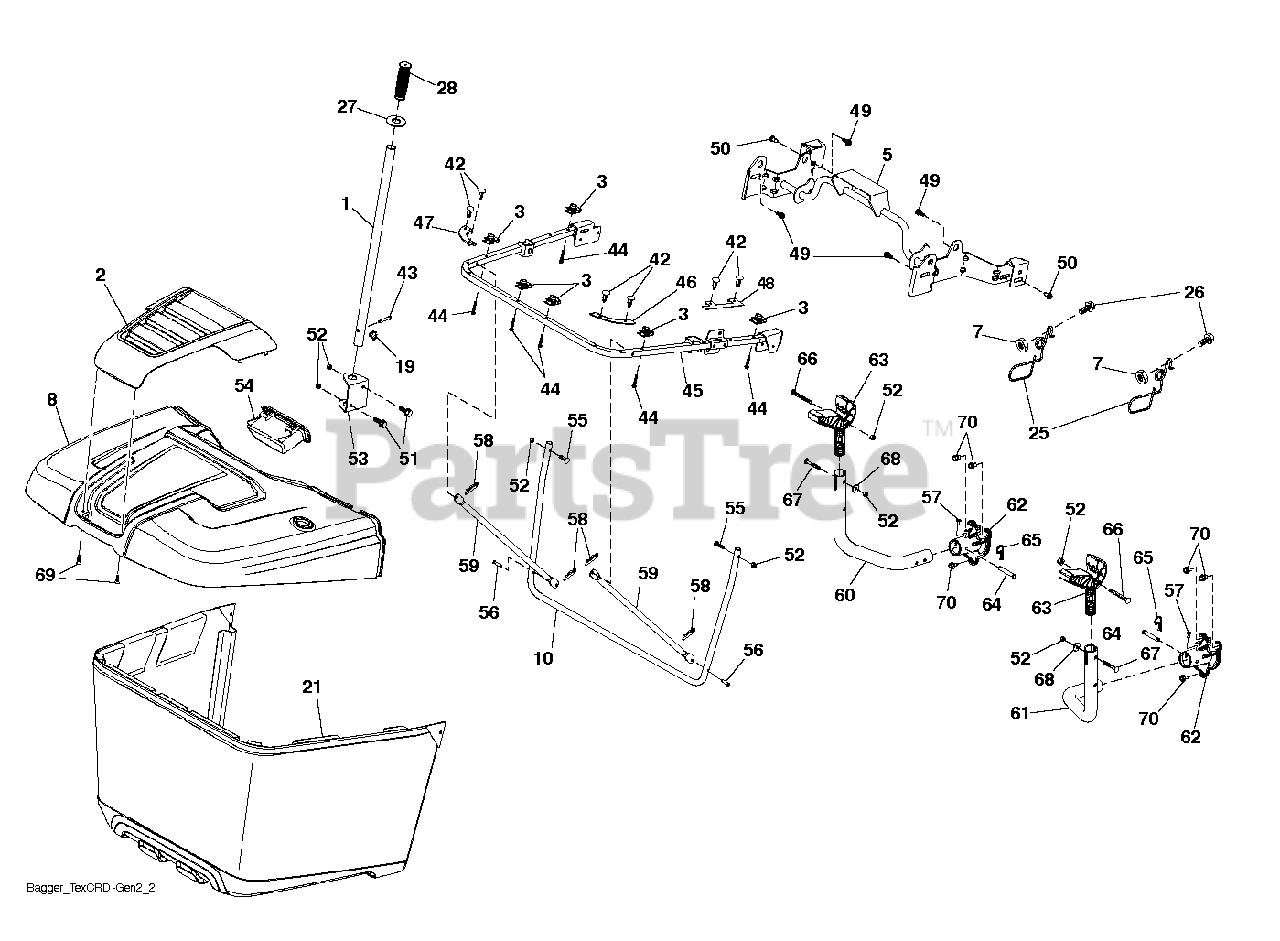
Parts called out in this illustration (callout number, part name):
1	TUBE.HANDLE.BAGGER.CRD/SRD.BLA
2	APPLIQUE.BAGGER
3	1/4-20 U NUT
5	FRAME TEX_CRD_GEN2 UPPER PIVOT
7	NUT T
8	BAGGER TOP
10	FRAME TEX_CRD_GEN2 BAGGER FRAM
19	PIN.COTTER.5/16.BOW TI
21	BAG FRAME BAGGER ASSEMBLY. HUS
25	LATCH LATCH. BAG. CRD GEN 2
26	SCREW HEX CRT
27	GROMMET RUBBER GROMMET, DUMP T
28	GRIP.HANDLE.BLACK
42	CLIP CHRISTMAS TREE CLIP
43	RIVET,DRILLED
45	FRAME TEX_CRD_GEN2 UPPER U FRA
46	CONNECTOR RIGHT BAGGER CORNER
47	CONNECTOR LEFT BAGGER CORNER C
48	BAFFLE BAGGER SIDE CLOSE-OUT
49	BOLT, SHOULDER 5/16-18
50	BOLT, 5/16-18 X 1 3/4
51	BOLT.CARR.SQNK.5/16-18UNC.X3/4
52	NUT.71038.31-18.HEX.NYLOCK
53	BRACKET DUMP HANDLE BRACKET, T
54	HANDLE BAGGER TOP FRONT HANDLE
55	BOLT
56	PIN.CLEVIS.183
57	SCREW T-30 1/4-20 X
58	RETAINER CLIP PM
59	TUBE BAGGER SPREADER TUBE, TEX
65	RETAINER M
69	SCREW,#8.FLAT.HEAD.DRILL.TIP
70	SCREW, 3/8-16X3/4
